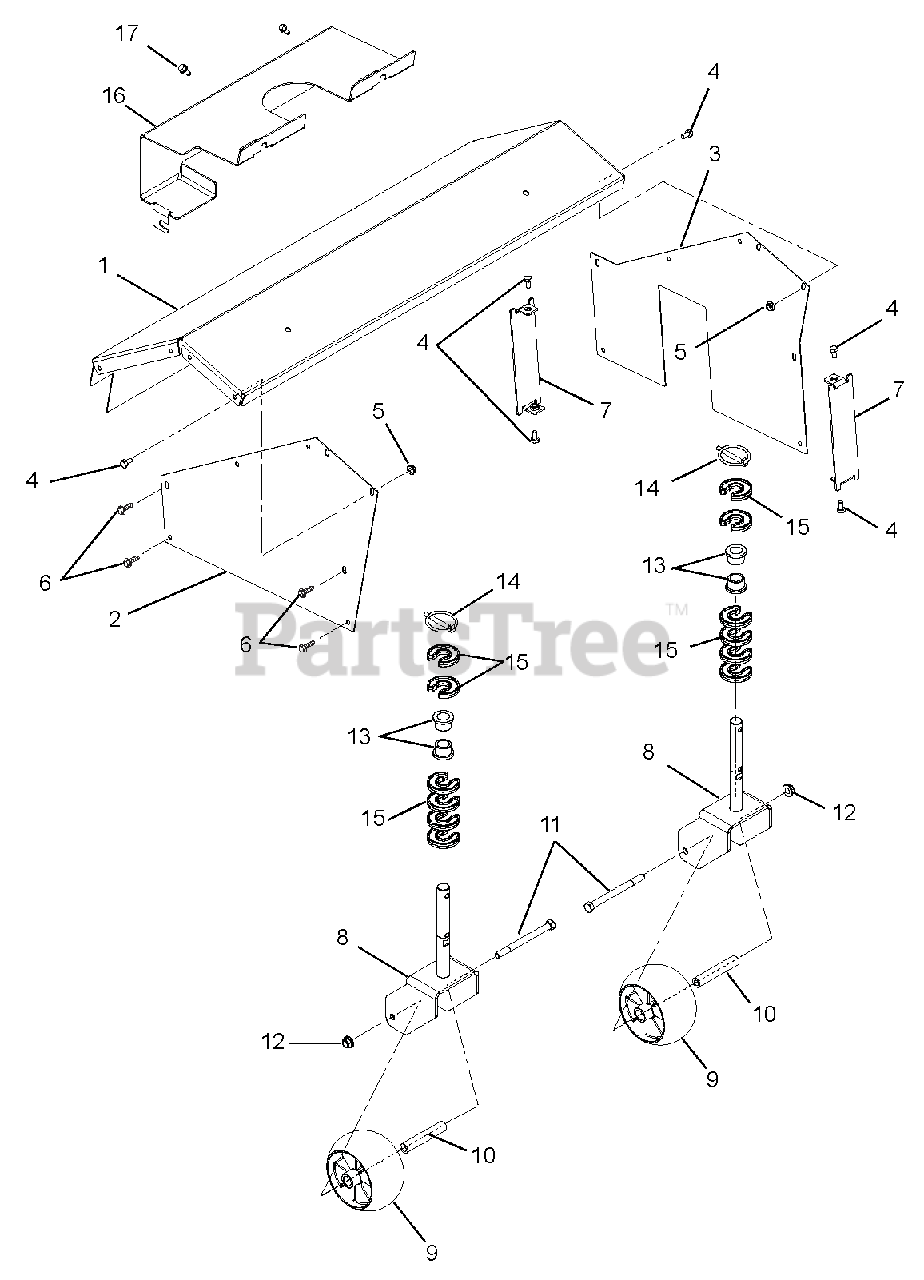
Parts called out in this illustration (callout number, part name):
1	COVER WITH DECALS, 28"BRUSH
2	COVER,RH SIDE BRUSH
3	COVER,LH SIDE BRUSH
4	@BLT-HEX .25-20X.50 GR5 YWZC
5	@NUT-LK-TOP-FLG .25-20 YWZC
6	SCR-TAP .25-20X.50 HWH TR YWZ
7	COVER,END
8	FORK, CASTER-BRUSH
9	ANTI-SCALP WHEEL - 5X3 CTR
10	SPACER, CASTER WHEEL
11	@BLT-HEX .38-16X4.50 GR5 YWZC
12	@NUT-LK-TOP-FLG .38-16 YWZC
13	BUSHING, FLANGE .75X.75X1.0
14	PIN, LYNCH - .25 X 1.25
15	CLIP-HOC FIXED
16	COVER, FRONT SHAFT - CE
17	SCR-TAP .25-20X.50 LGHWH TR YZ
